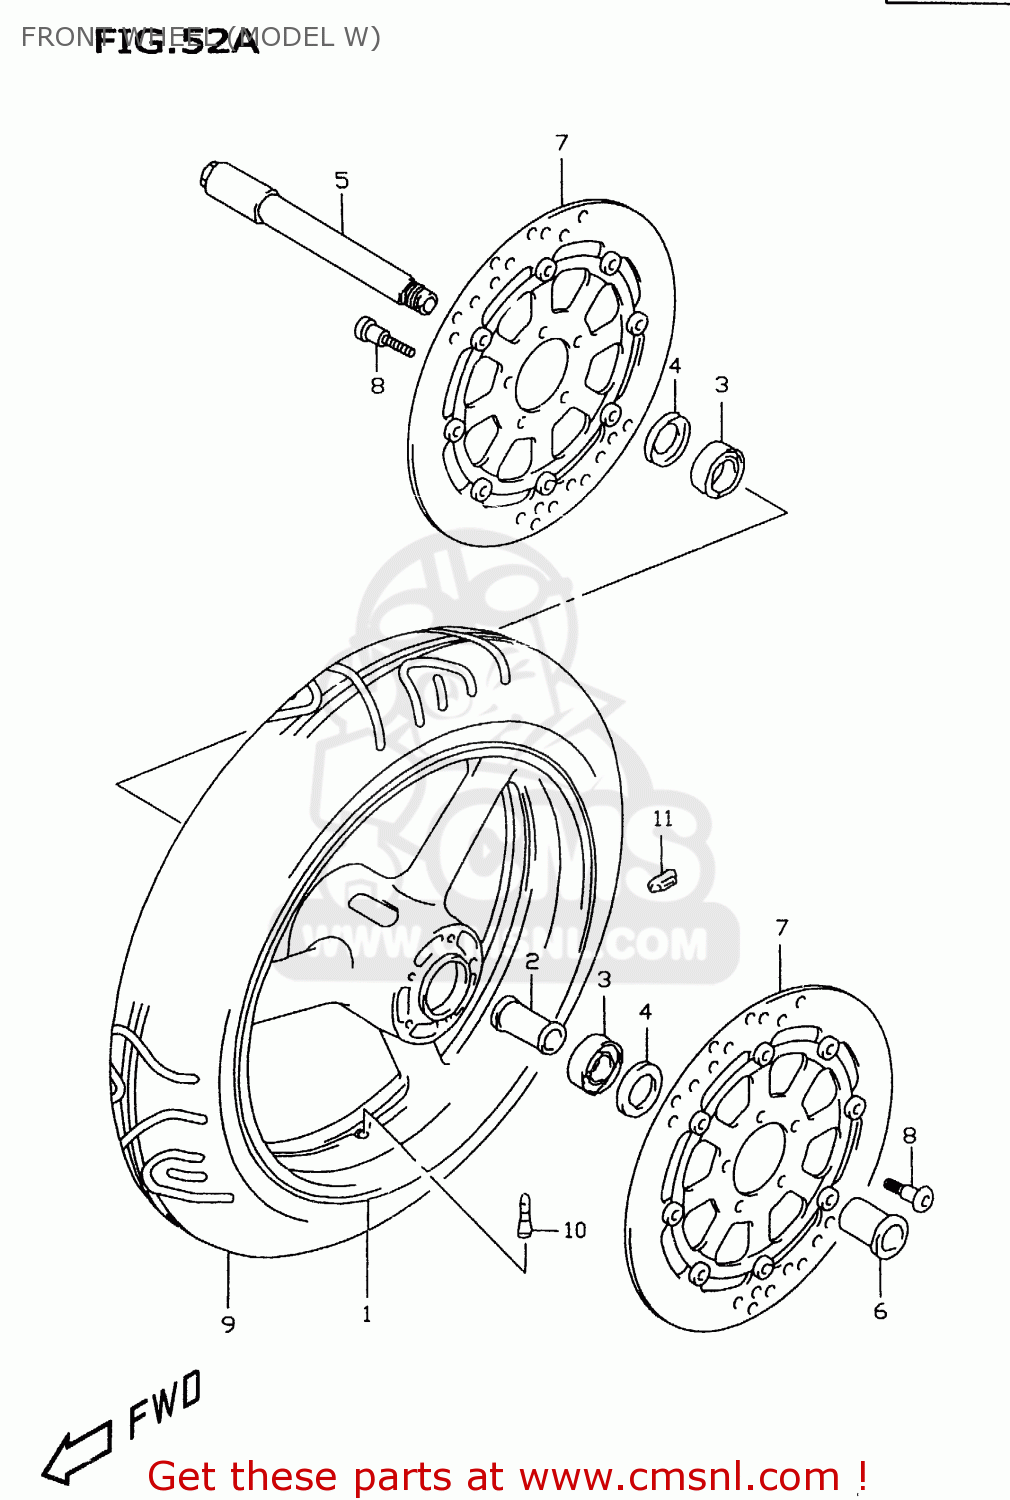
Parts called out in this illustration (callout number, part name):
1	WHEEL,FRONT (17XMT3.50)(
2	SPACER,FRONT HUB BEARING
3	BEARING(25X52X15)
4	SEAL,OIL(32X52X7)
5	AXLE,FR
6	NUT,FR AXLE
7	DISC,FR BRAKE
8	BOLT 8X33
9	TIRE,FRONT 120/70 ZR17
10	VALVE ASSEMBLY,WHEEL,TR412
11	BALANCER,WHEEL (10G)
